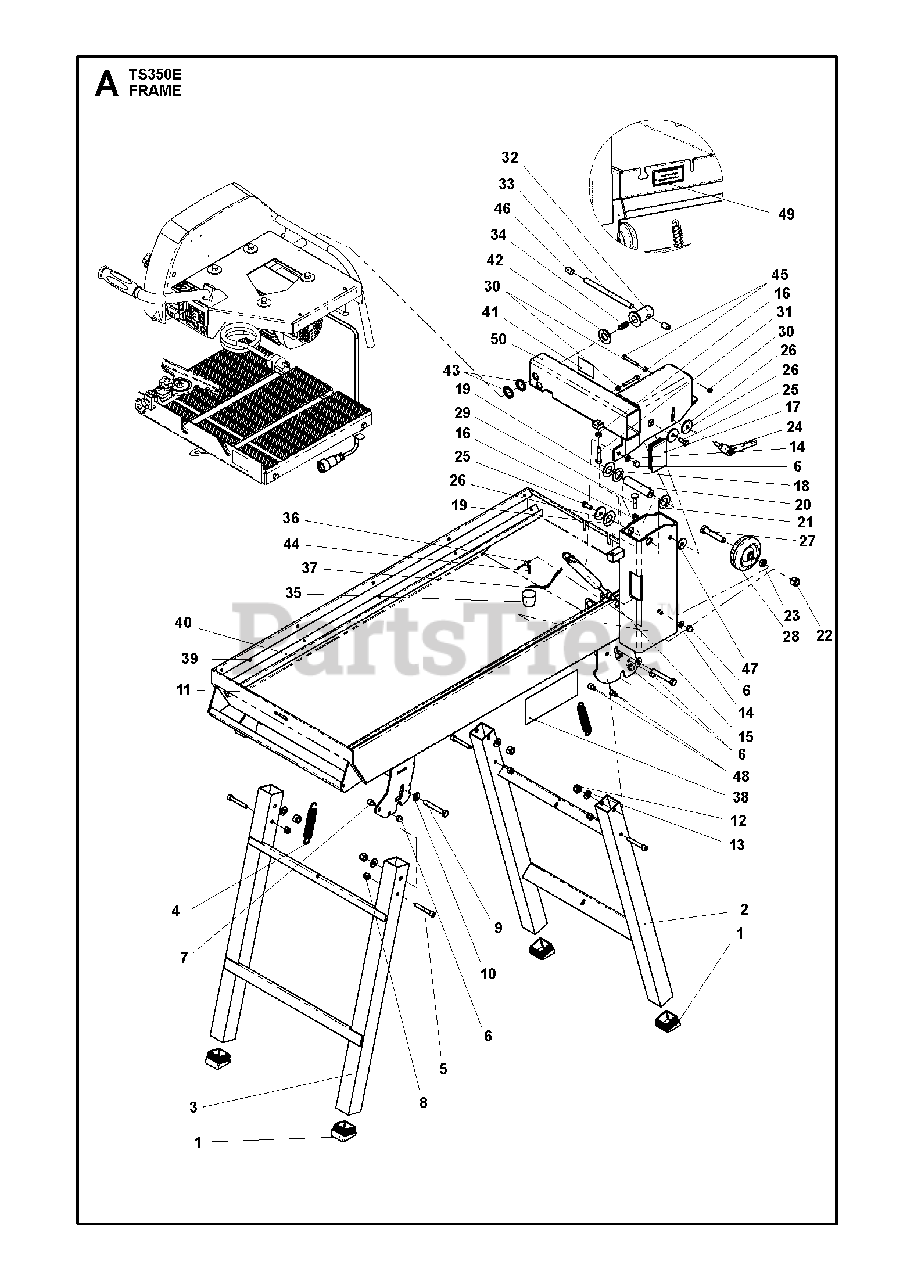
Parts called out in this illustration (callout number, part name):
1	FEET PAD ON TS350E/TS400***543
8	HEXAGON LOCKING NUT
10	WASHER
12	HEXAGON LOCKING NUT
13	WASHER
14	WASHER
16	HEXAGON NUT
17	EMBOUT RECT.GPN270R80504/
19	RONDEL RESSOR40X20,4X1,5/
38	STICKER, LEGS FOLDING
46	EMBOUT 12/18 NOIR 220/
49	UTILISATION DE LA POMPE/
